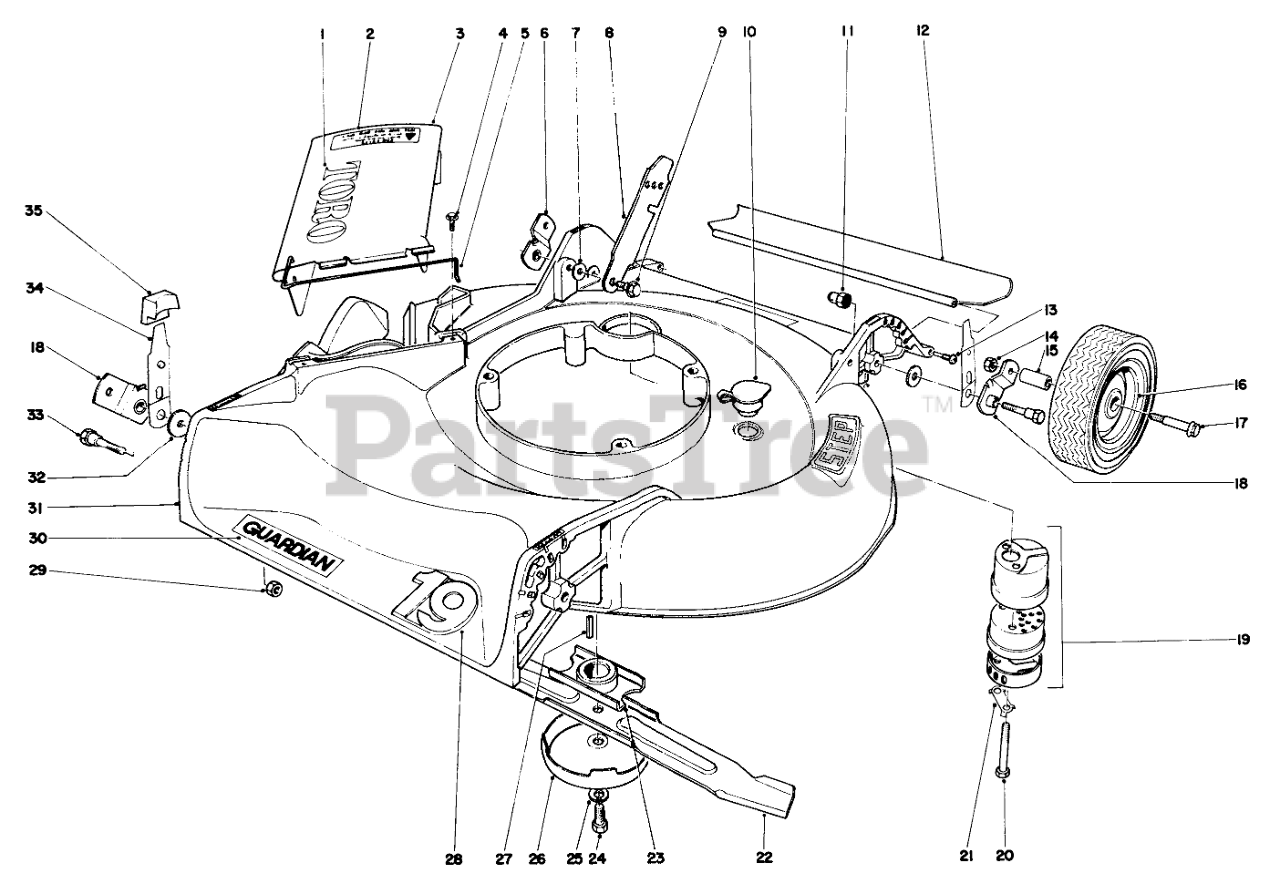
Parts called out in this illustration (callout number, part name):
1	TORO LOGO DECAL
2	Caution Decal
3	Deflector Cover (Incl. Ref. No. 1-2 & 5)
4	SCREW
5	Hinge Spring
6	Pivot Arm
7	SPACER
8	Latch
9	SCREW-SHOULDER
10	WASHOUT PLUG
11	HANDLE PIVOT NUT
12	SHIELD - TRAILING
13	SAFTEY SHIELD SCREW
14	Nut
15	Bushing
16	Wheel & Tire Assembly (Incl. No.15) (Model 19400)
18	Pivot Arm
19	Muffler Assembly (Incl. Ref. Nos. 20-21)
20	SCREW-HH
21	CLIP - LOCKING
22	Blade
23	Blade Retailer
24	SPECIAL SCREW
25	WASHER-LOCK
26	AntiScalp Cup
27	KEY-SQUARE
28	Emblem Deck
29	Nut
30	Decal
31	Housing
32	WASHER-PIVOT
33	5/16-18 PIVOT SCREW
34	SPRING ARM ASM
35	Knob
